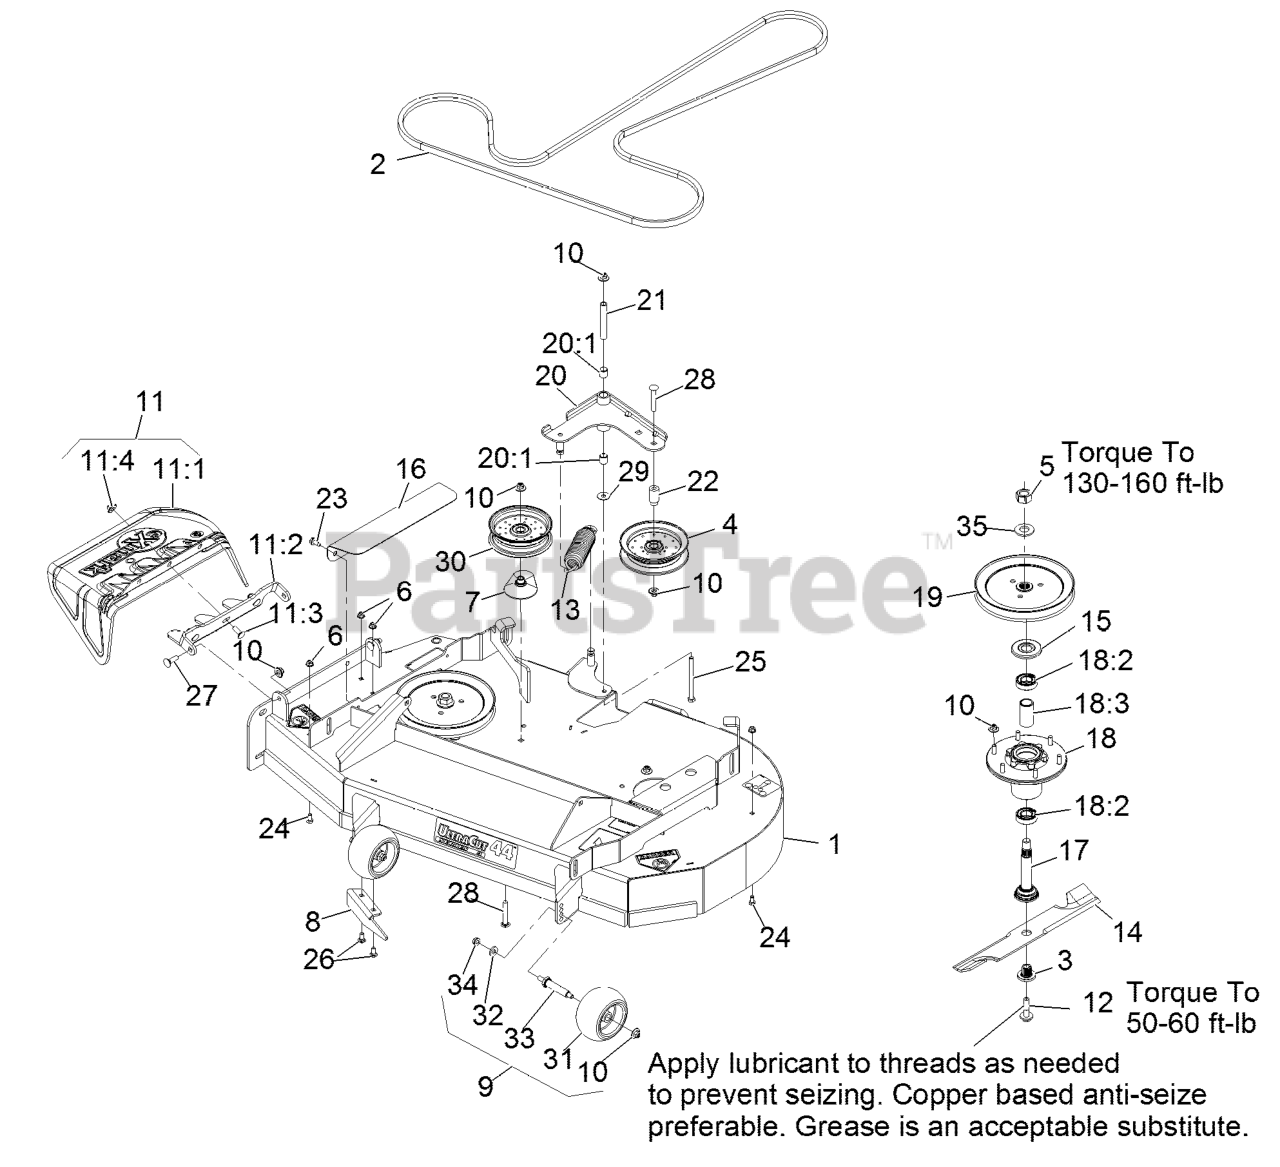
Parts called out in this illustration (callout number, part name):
1	ASM-DECK W/DECALS 44
2	BELT - V, B
3	BUSHING,SPLINED
5	NUT-HEX
6	NUT-HF, NI
7	SPACER-PULLEY
8	BAFFLE-DISCHARGE
10	Nut-Nyloc 3/8-16 Flg
11	ASM,DISCHARGE CHUTE
11:1	CHUTE,DISCHARGE
11:2	BRACKET,DISCHARGE CHUTE
11:3	SCREW-CARR
11:4	Nut-Nyloc 3/8-16 Flg
12	SCREW,SEMS 1/2-20 X 2.19
13	SPRING-EXTENSION
14	Blade-Mulch, 22.25
14	Blade-Notched, 22.25
15	GUARD,BEARING TOP .989
16	COVER,BELT
17	ASM-SPINDLE AND SEAL
18	ASM-CUTTER HSG WITH BEARINGS
18:2	BEARING-BALL
18:3	SPACER-BEARING
19	SHEAVE-BLADE DRIVE, 8.40
20:1	SLEEVE-BEARING
21	BUSHING
22	BUSHING-IDLER
23	Screw-HWH 5/16-18 X 3/4 Tf
24	SCREW-HH
25	SCREW-HH
26	BOLT-CARR
27	BOLT-CARR
28	SCREW-CARR
30	IDLER-PULLEY, FLAT
31	ROLLER-SCALP, ANTI
32	WASHER-BELLEVILLE
34	NUT-HHF, WHIZ
